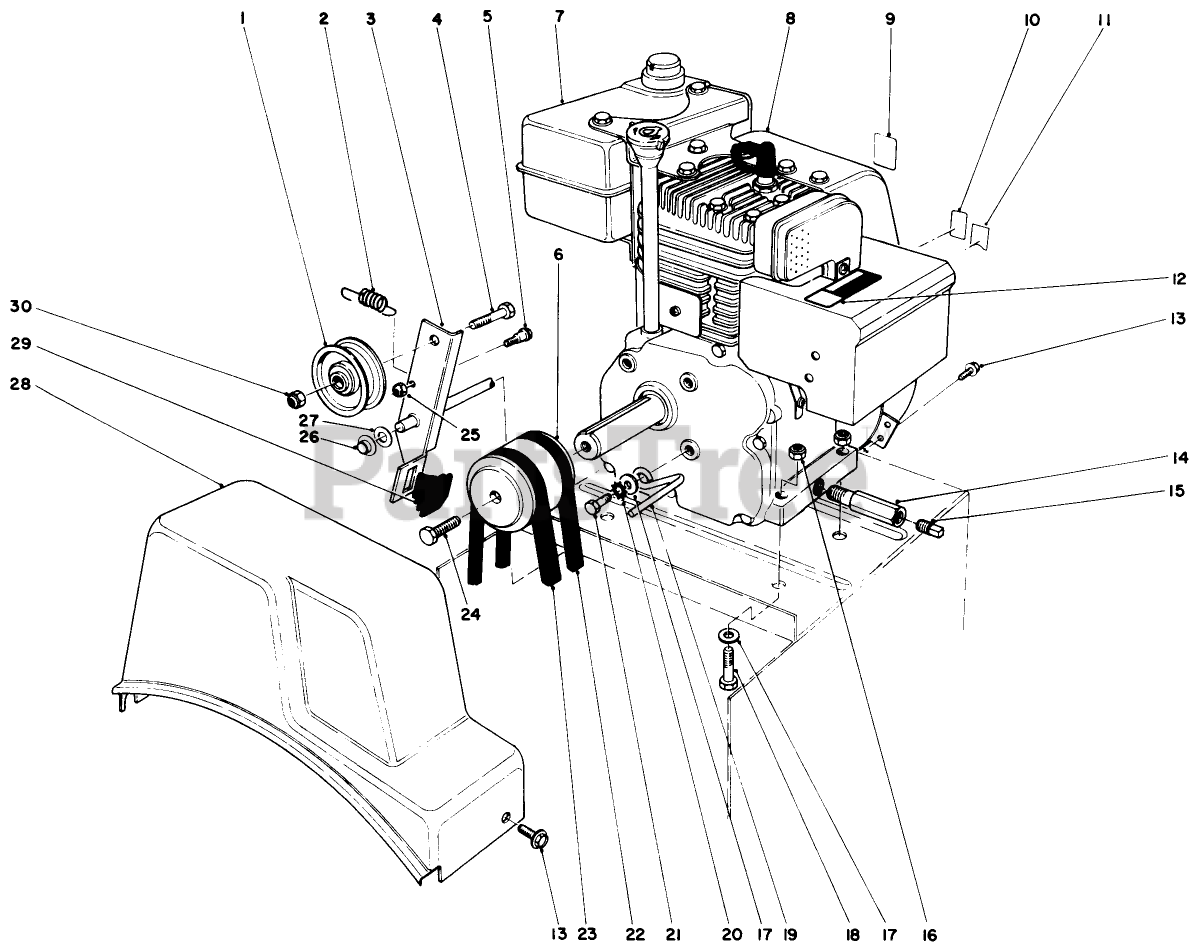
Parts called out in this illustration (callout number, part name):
1	PULLEY-IDLER
2	SPRING
3	Auger Clutch (Incl. Ref. #29)
4	SCREW-HH
5	BOLT-SHOULDER
6	PULLEY-ENGINE
7	GAS TANK 2 QT W CAP
9	DECAL-PRIMER
10	THROTTLE DECAL, INT'L
11	DECAL-CHOKE
12	DECAL-HOT SURFACE, WARNING
13	SCREW-HWH
14	PIPE-NIPPLE
15	CAP-PIPE
16	NUT-LOCK, NI
17	WASHER-PLAIN
18	SCREW-HH
19	RETAINER-BELT
20	WASHER-LOCK
21	SCREW-HH
22	V BELT-3L, TRACTION
23	V-BELT (29.50 INCH)
24	SCREW-SPECIAL
25	NUT-LOCK, NI
26	RETAINER-PUSH ON
27	WASHER-FLAT
28	COVER-BELT
29	PAD-BRAKE
30	NUT-LOCK, NI
